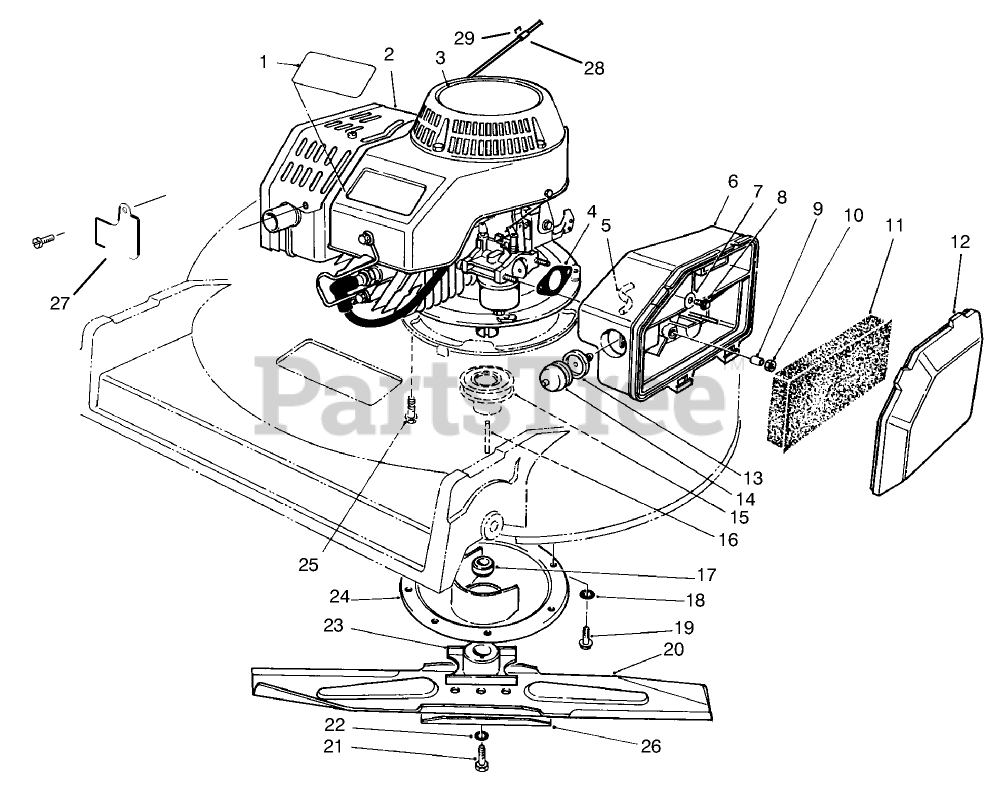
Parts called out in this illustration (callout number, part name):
1	DECAL - PROLINE
3	DECAL-2 CYC RECOIL COMM
4	GASKET-AIR CLEANER
5	HOSE-PRIMER F
7	WASHER-FLAT
8	SCREW-HH
9	SPACER
11	ELEMENT-AIR CLEANER
12	COVER-AIR CLEANER
13	BODY-PRIMER
14	BULB-PRIMER
15	PULLEY-DRIVER
16	KEY-SQUARE
17	SPACER-BLADE RETAINER
18	WASHER-LOCK, INTERNAL
19	SCREW-HWHTF
21	SCREW-BLADE
22	WASHER-LOCK
25	SCREW-HHF
27	EXTENSION-MUFFLER GUARD
29	Staple
